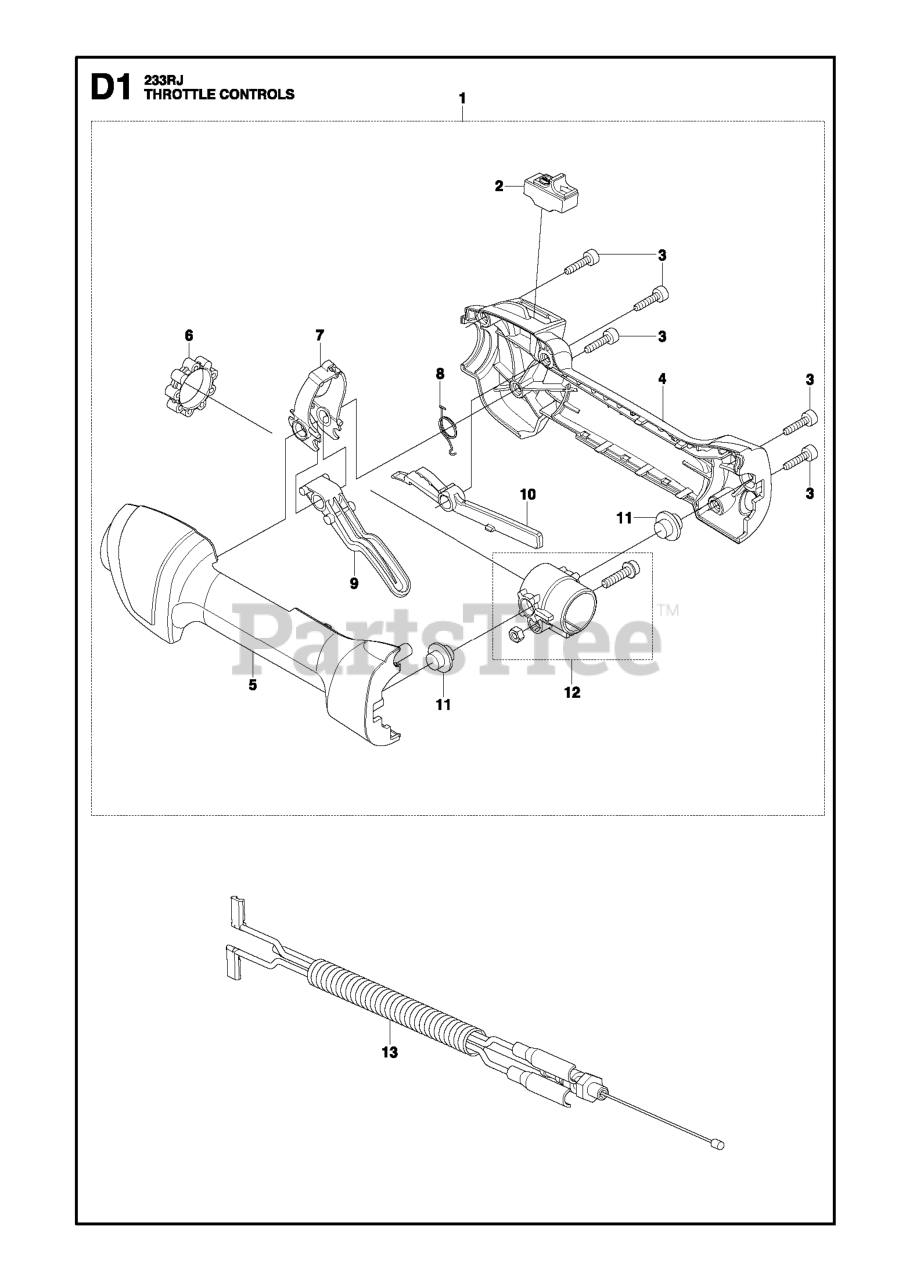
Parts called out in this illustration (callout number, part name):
2	START/STOP SWITCH
6	VIBRATION DAMPER
8	RETURN SPRING
9	THROTTLE TRIGGER
10	THROTTLE LOCK
